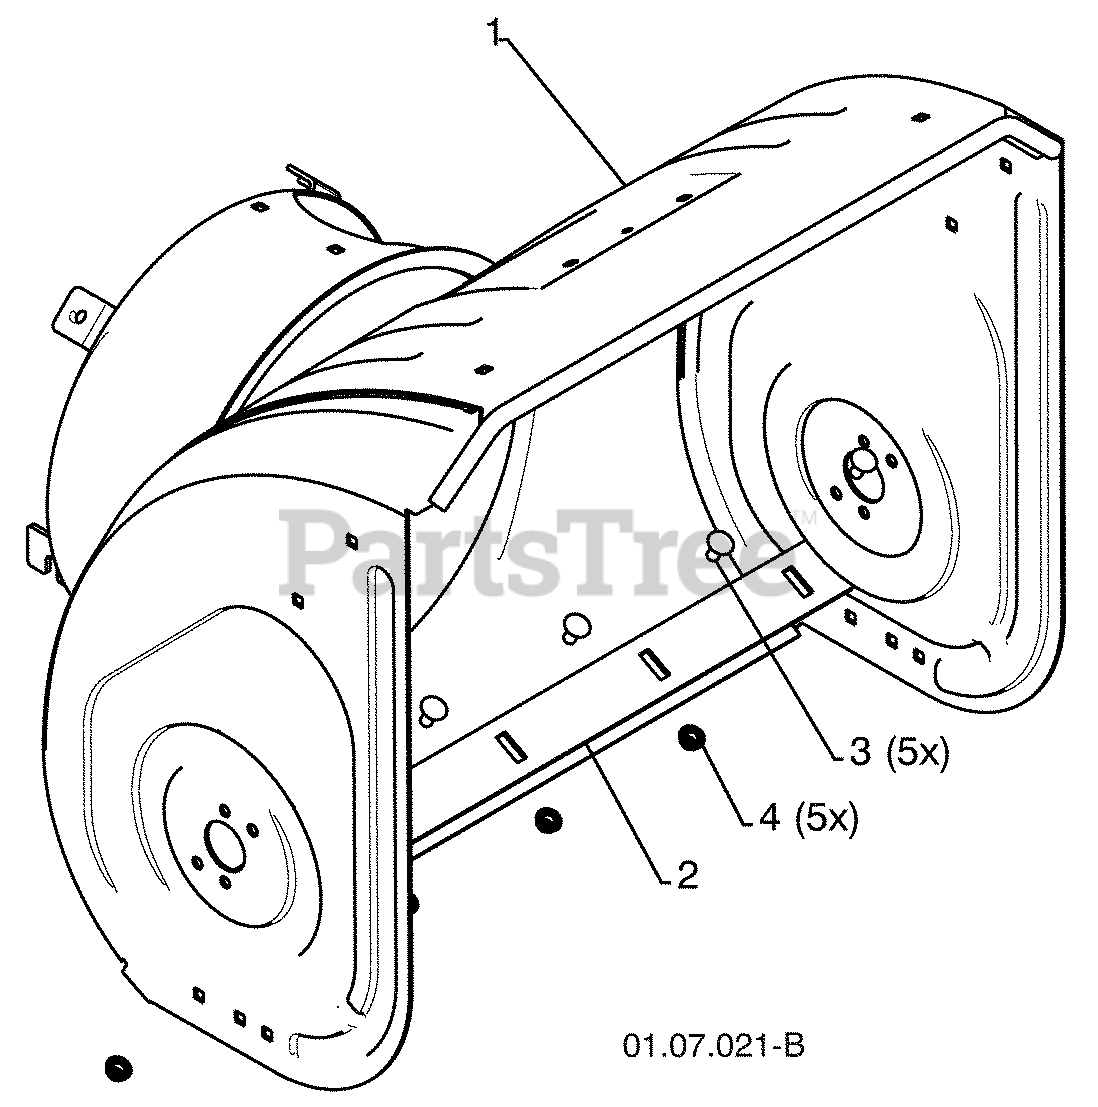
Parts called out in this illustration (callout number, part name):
1	AUGER HOUSING
2	SCRAPPER BAR
3	CARRIAGE BOLT 5/16-18 X .625
4	NUT 5/16-18
